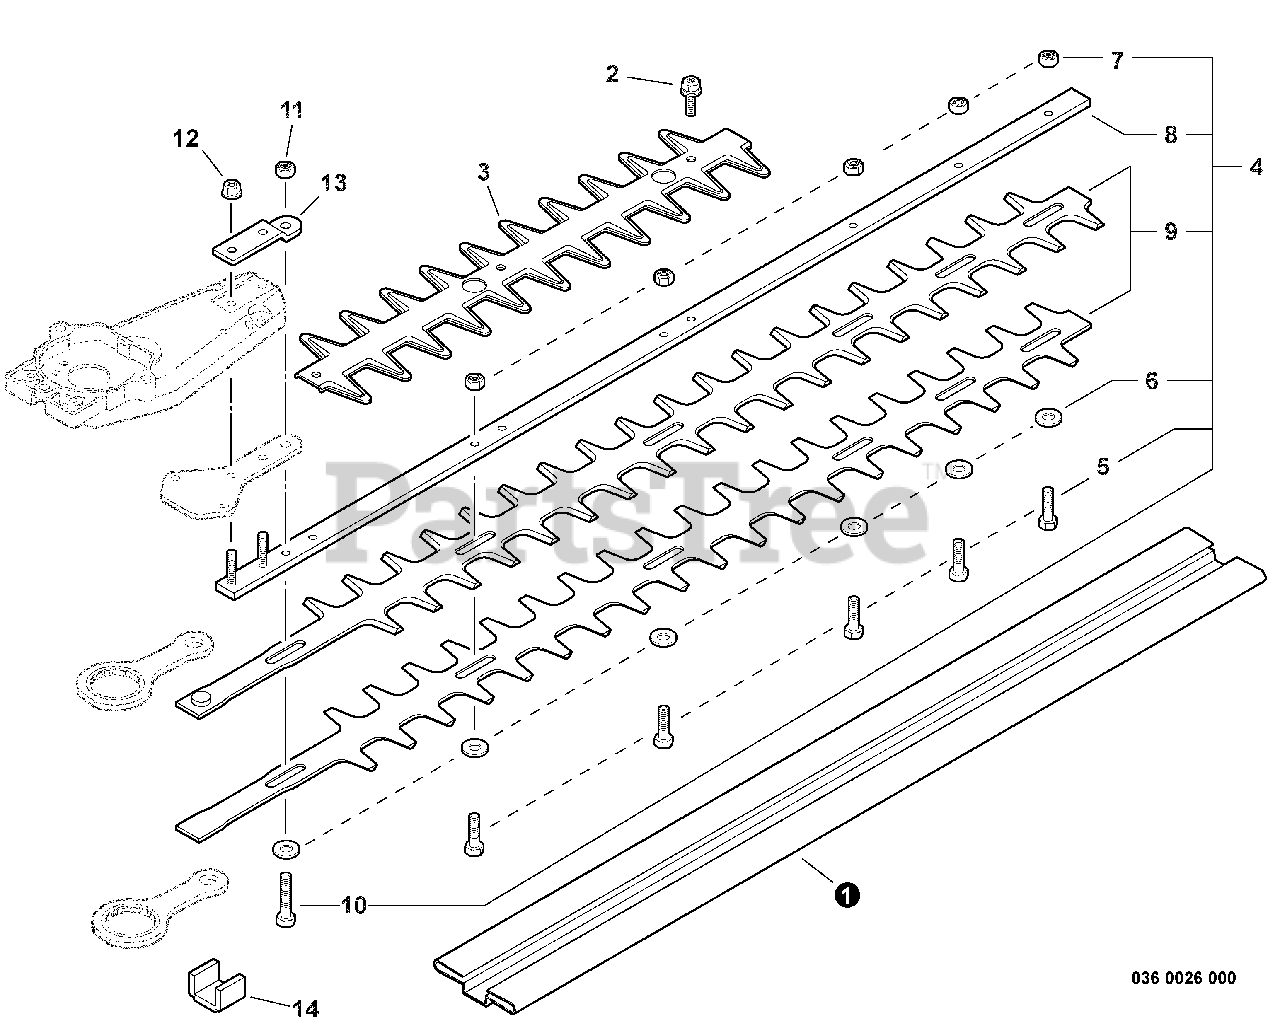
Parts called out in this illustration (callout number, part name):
1	SCABBARD 30"
2	BOLT M5×8
3	GUARD, CUTTER BLADE
4	CUTTER ASSY, 30"
5	BOLT M6×20
6	WASHER M6
7	NUT, LOCK M6
8	GUIDE BAR, 30"
9	BLADE, 30"
11	NUT, LOCK M6
12	NUT, FLANGE M5
13	BRACKET, CUTTER
14	PACKING, FELT
